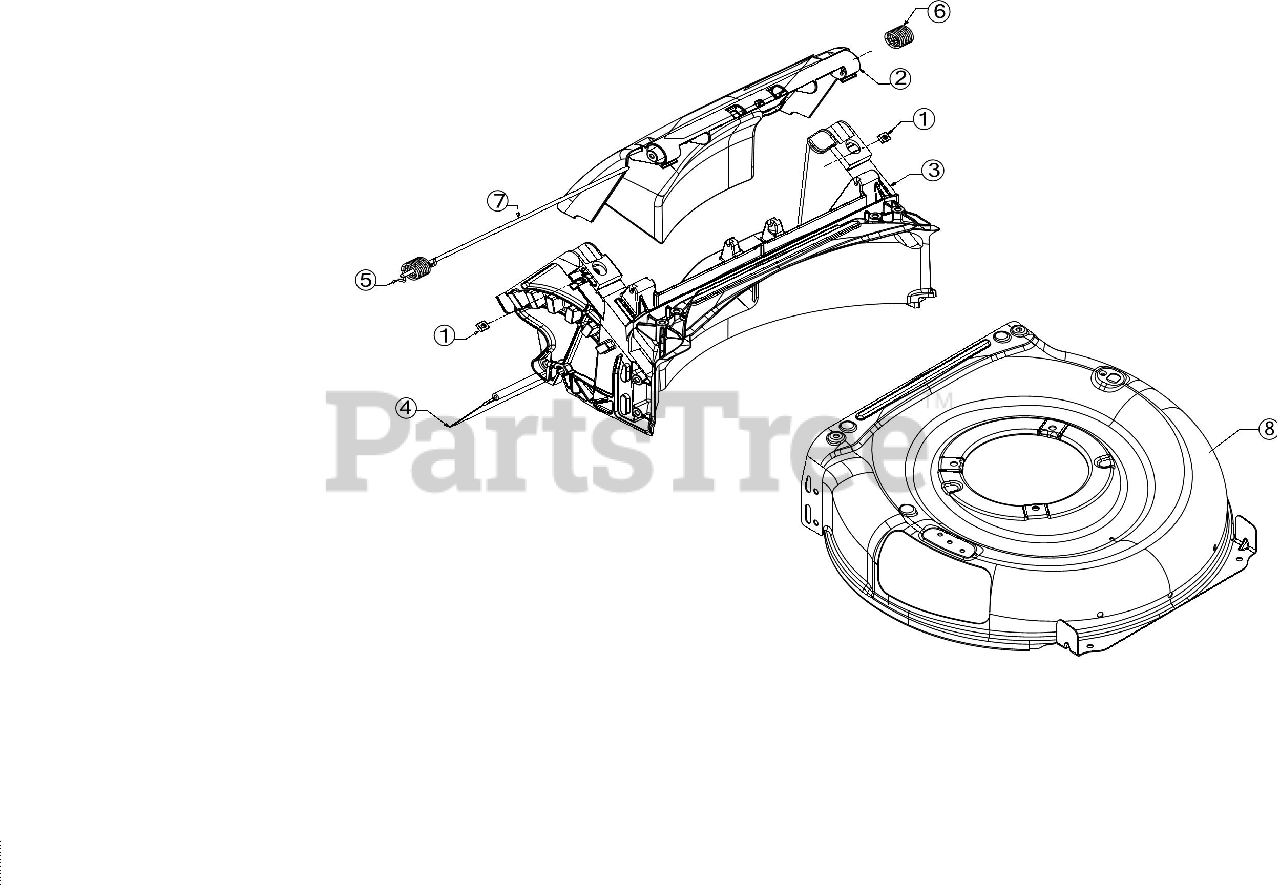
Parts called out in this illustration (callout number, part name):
1	SQUARE NUT 1/4-20
3	DOOR ASSEMBLY
4	TRAILSHIELD
5	TORSION SPRING (RH)
6	TORSION SPRING (LH)
7	REAR DOOR PIVOT ROD
8	DECK-21" 3IN1 SP
